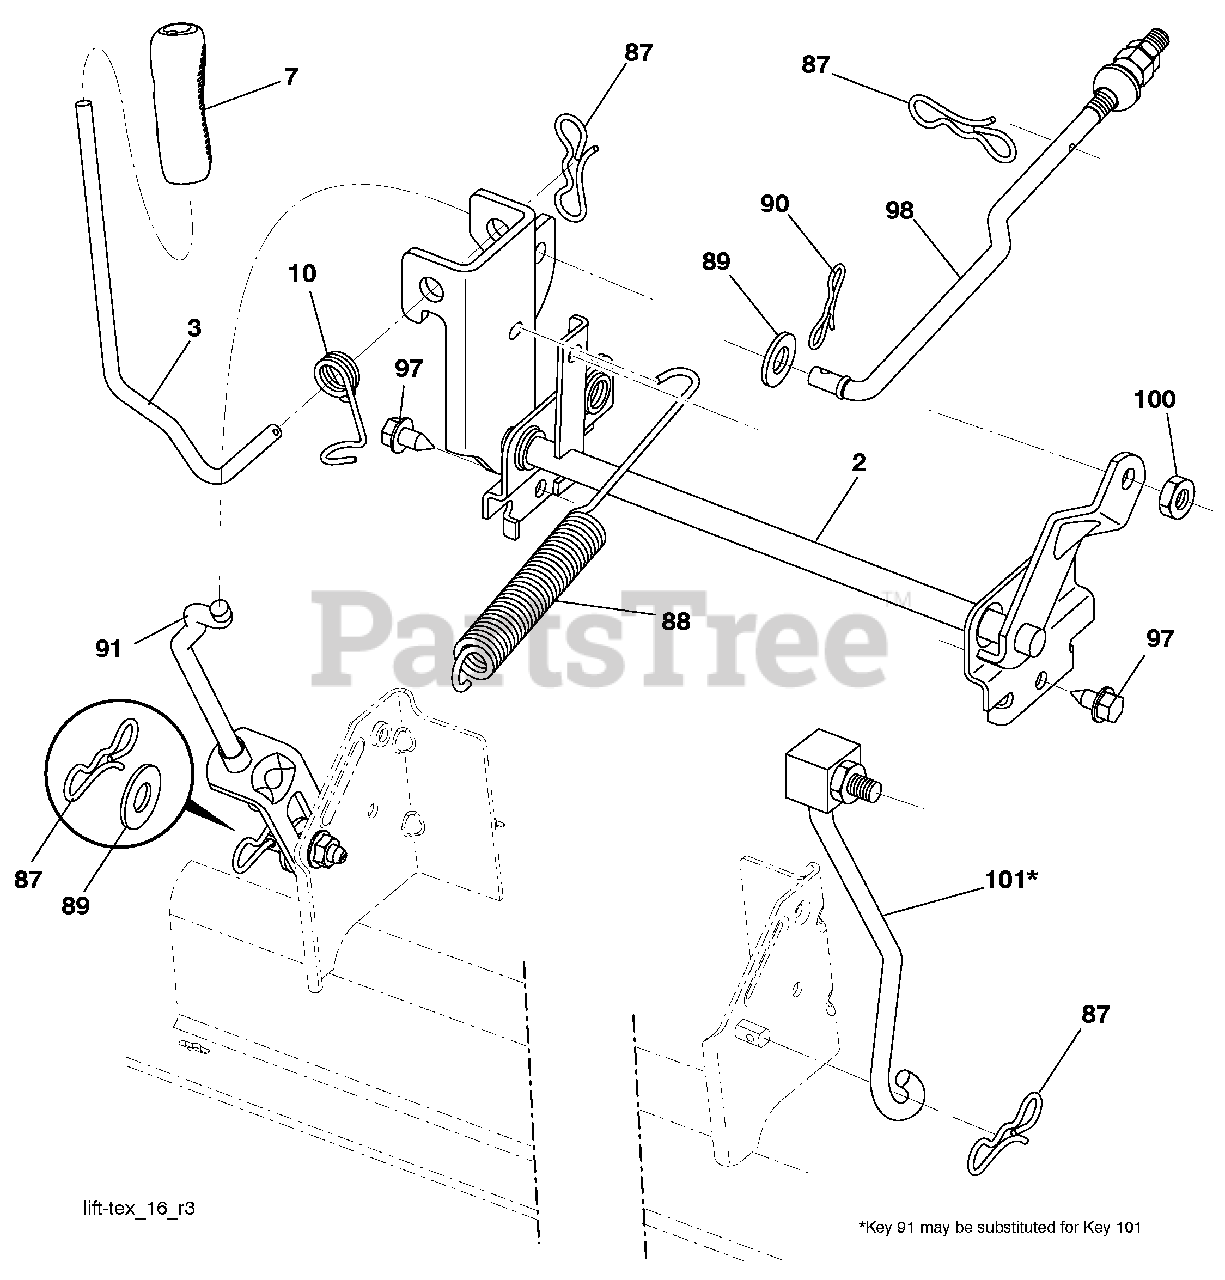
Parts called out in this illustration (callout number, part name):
2	Shaft Asm., Lift
3	Lever Asm., Lift RH
7	Grip, Lever
10	Spring Torsion
87	Pin Cotter 7/16 Bow Tie Lock
88	Spring Lift Assist
89	Washer Clear Zinc
90	Pin Cotter 5/16 Bow Tie Lock
91	Link Asm. Lift Rear
97	Screw 3/8-16 x .75 Smgml Tap/R.Z
98	Link Lift Susp. Front Mower
100	Nut Centerlock 3/8-16 unc
101	Link Asm. Lift Fixed
